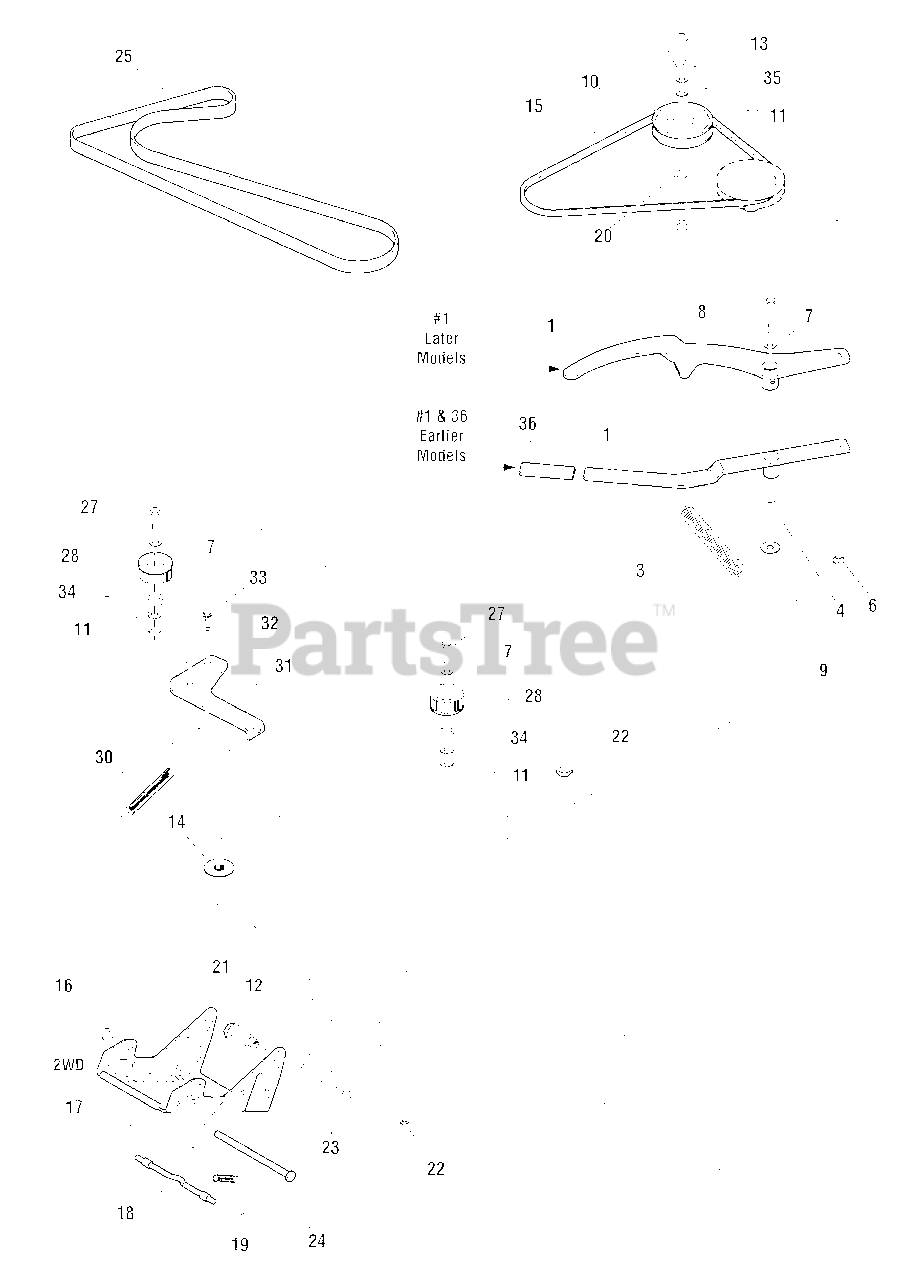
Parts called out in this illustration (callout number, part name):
1	IDLER ARM ASSEMBLY, w/Bushings
3	SPRING, Extension
6	BOLT, Carriage, 3/8-16 X 2 1/2
7	WASHER
8	CAPSCREW, Hex Head, 3/8-16 x 3, G8
9	WASHER
10	PULLEY, 4-1/2 OD
11	WASHER
12	SPACER, 3/8 x 3/4 x 3/4
13	NUT, Hex Lock ESNA, 3/8-16
14	WASHER & LOCK NUT ASSEMBLY, 3/8-16
16	NUT, Push
17	HITCH, Mower
18	ROD, 3/8 x 8
19	SPRING, Extension
21	NUT, Hex Flange, 3/8-16
22	NUT, Hex Flange Lock, 3/8-16
23	CAPSCREW, Hex, 3/8-16 x 1-3/8
25	BELT, Timing
27	CAPSCREW, Hex Head, 3/8-16 x 2
28	PULLEY, Idler
30	SPRING, Extension
31	ARM, Idler
33	CAPSCREW, Hex Head Taptite, 5/16-18 x 5/8
34	HUB, Pulley
35	STOP, Belt
36	Grip, Black
